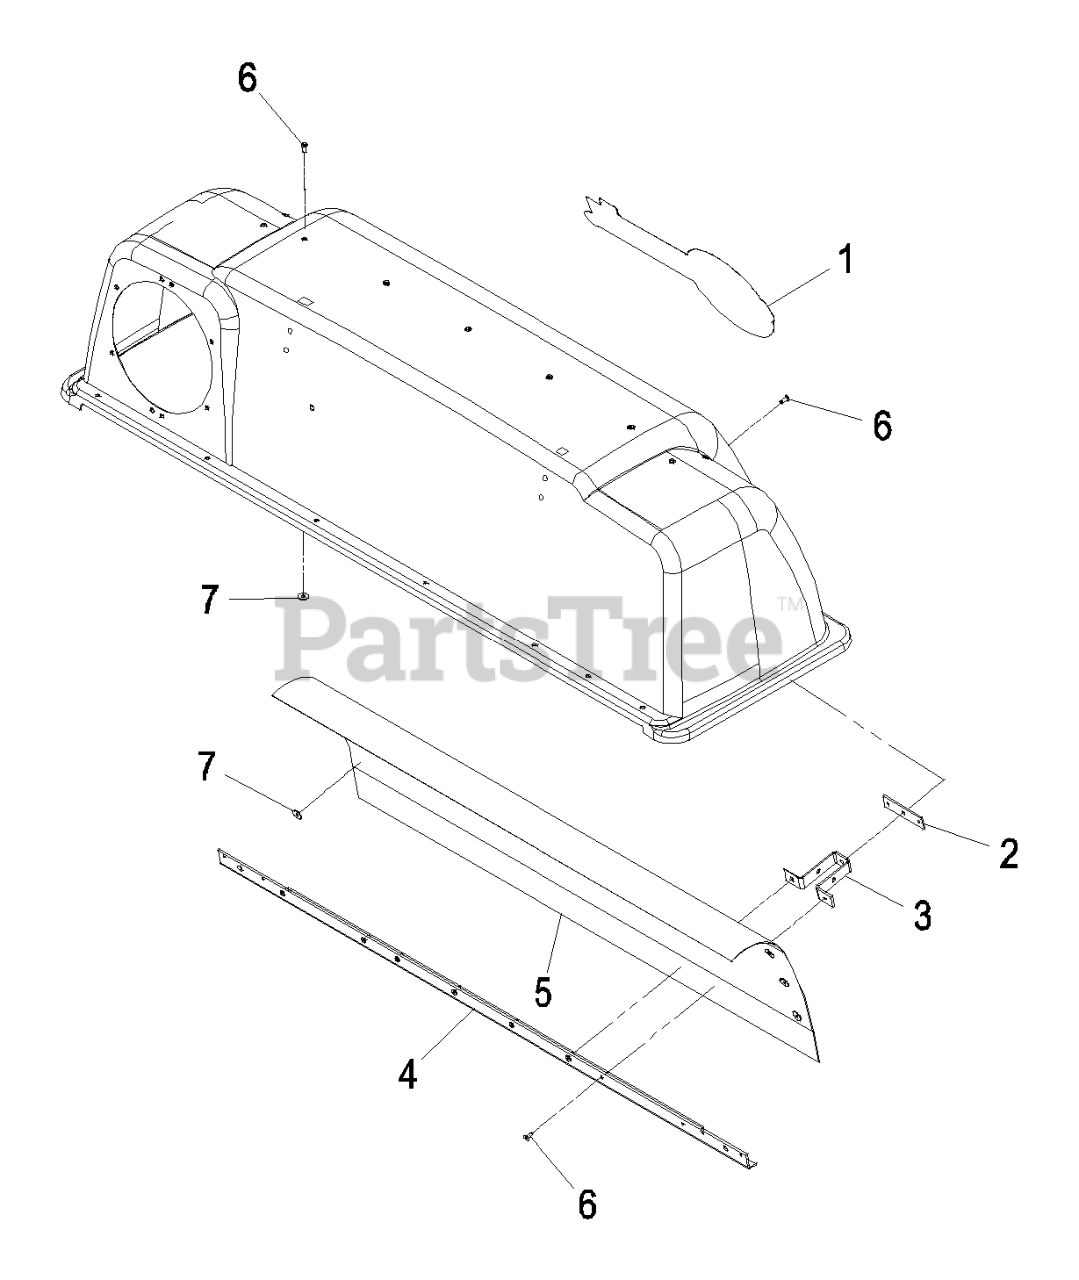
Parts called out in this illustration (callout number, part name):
1	DECAL, EXMARK
2	PLATE-LATCH, REINFORCEMEN
3	BRACKET-MOUNT
4	SUPPORT-SCREEN
5	SCREEN-BAGGER
6	RIVET-BLIND
7	WASHER-FLAT
